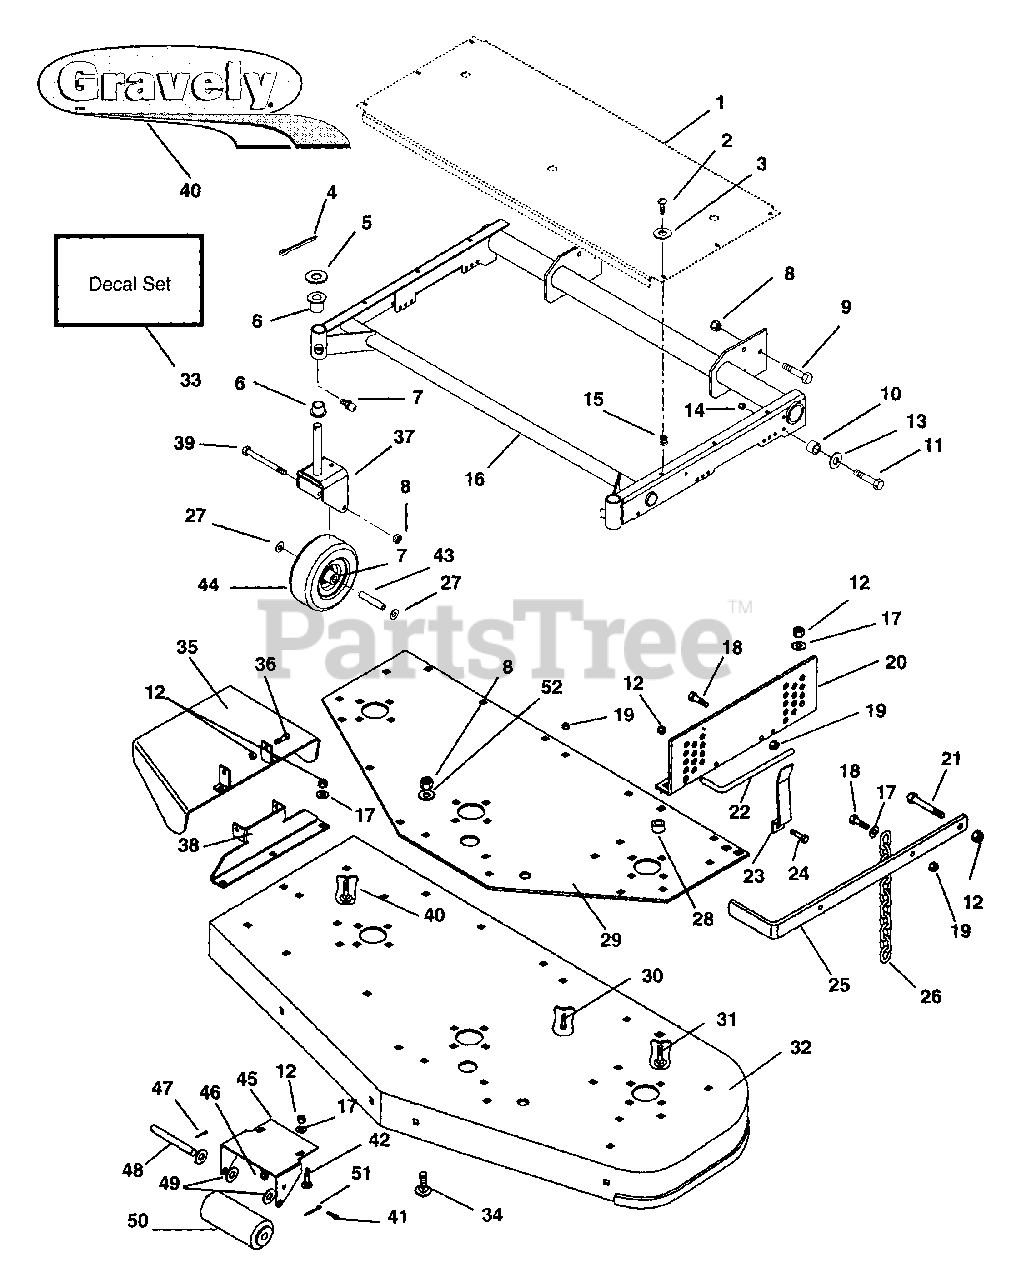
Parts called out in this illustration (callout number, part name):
1	Guard, Belt 60"
2	Screw-Tap .250-20 x .50
3	Washer-Flat-Steel .281 x .625 x .065
4	Pin-Cotter .188 x 1.500
5	Washer-Hardened-Thrust 1.002 x 1.552 x .030
6	Bushing-Flange 1.020 x 1.385 x .75 x 1.75
7	Fitting-Lube .25-28 x .256
8	Nut-Locking-Nylon .50-13 Grade 5
9	Bolt-Hex .50-13 x 1.50 Grade 5
10	Bushing .391 x .626 x .670
11	Bolt-Hex .38-16 x 1.50 Grade 5
12	Nut-Locking-Nylon .375-16 Grade 2
13	Washer-Flat-Steel .390 x 1.5 x .125
14	Nut-Locking-Nylon .375-16 w/ Insr Grade 2
15	Grommet, Plastic
16	Weldment, Mower Frame
17	Washer-Flat-Steel .406 x .812 x .065
18	Bolt-Hex .31-18 x 1.00 Grade 5
19	Nut-Locking-Nylon .312-18 Grade 2
20	Bracket, Mower Support Left Hand
20	Bracket, Mower Support Right Hand
21	Bolt-Hex .38-16 x 2.0 Grade 5
22	Pin, Mower Locking
23	Spring, Pin
24	Bolt-Hex .38-16 x .75 Grade 5
25	Bar, Lift
26	Chain, Height Adjuster
27	Washer-Hardened .760 x1.25 x .094
28	Bushing .406 x .750 x .188
29	Plate, 60" Support
30	Bolt-Hex .31-18 x .75 Grade 5
31	Bolt-Round Head Square Neck .38-16 x 1.25
32	Weldment, 60" Mower
33	Decal Set - Deck
34	Bolt-Round Head Square Neck .50-13 x 1.00
35	Weldment, Discharge Chute
36	Bolt-Hex .375-16 x 1.00 Grade 5
37	Weldment, Caster Fork
38	Bracket, Discharge
39	Bolt-Hex .50-13 x 5.50
40	Decal, Gravely Logo
41	Bolt-Hex .25-20 x .75 Grade 5
42	Bolt-Round Head Square Neck .38-16 x 1.0
43	Bearing, Gauge Wheel .750 x .532 x 3.97
44	Wheel 9 x 3.50
45	Bracket, Roller Right Hand
46	Nut-Locking-Nylon .250-20 Grade 2
47	Pin-Cotter .25 x 1.00
48	Shaft, Center Roller
49	Washer-Flat-Steel .656 x 1.312 x .095
50	Roller, Gauge
51	Pin-Cotter .250 x 2.00
52	Washer-Flat-Steel .50 x 1.25x .083
